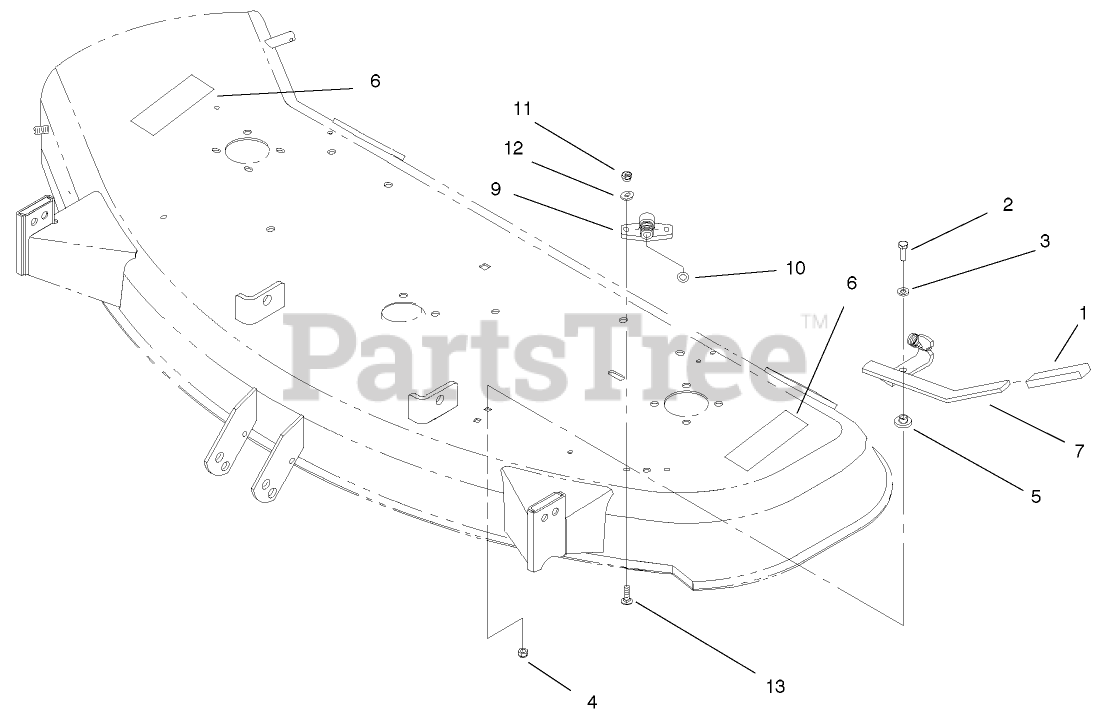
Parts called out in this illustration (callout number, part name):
2	SCREW-HH
3	WASHER-PLAIN
4	NUT-LOCK, NI
5	SPACER-RACK, STEERING
6	DECAL-DANGER
7	LEVER ASM
10	O-RING
11	NUT-LOCK, NI
12	WASHER-FLAT
13	BOLT-CARR
